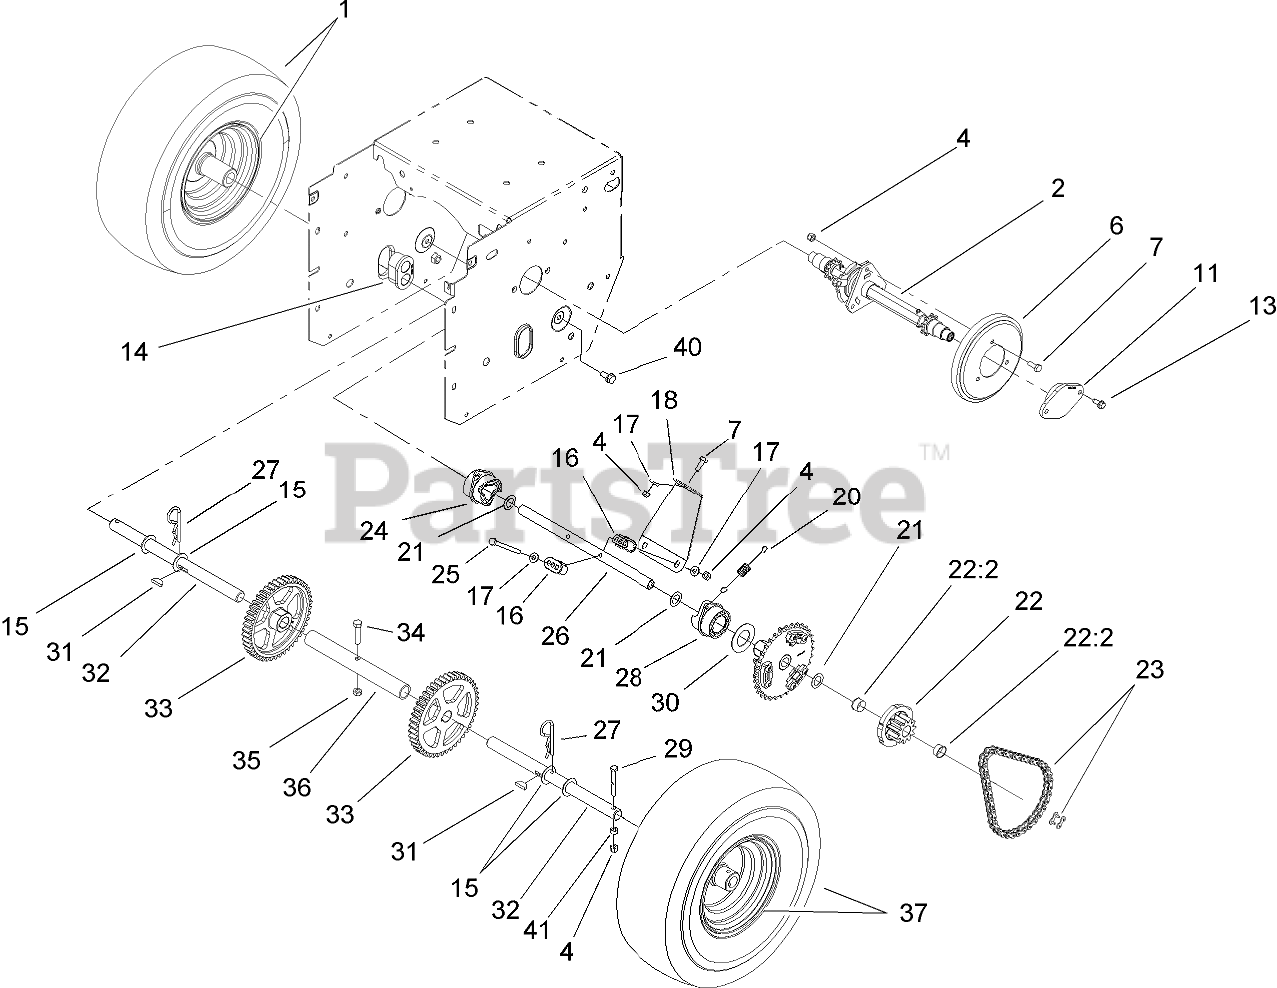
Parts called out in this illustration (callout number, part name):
1	RH WHEEL AND TIRE ASM
1	RIM-TIRE
2	CLUTCH HEXSHAFT ASM
4	NUT-LOCK, NI
6	WHEEL-FRICTION
7	SCREW-HH
11	RETAINER-BEARING
13	SCREW-HWH
14	BEARING-AXLE
15	WASHER-THRUST
16	GUIDE-COLLAR
17	WASHER-FLAT
18	BRACE-COLLAR, SHIFT
20	SPRING-EXTENSION
21	WASHER-FLAT
22	11T GEAR ASM
22:2	BUSHING-FLANGE
23	CHAIN-ROLLER
23	LINK-CONNECTING
24	COLLAR-SHIFT, RH
25	SCREW-HH
26	SHAFT-INTERMEDIATE
27	PIN-HAIR
28	COLLAR-SHIFT, LH
29	SCREW-HH
30	WASHER-THRUST
31	KEY-WOODRUFF
32	SHAFT-AXLE
33	GEAR-AXLE, 44 TOOTH
34	SCREW-HH
35	NUT-LOCK, NI
36	TUBE-AXLE
37	LH WHEEL AND TIRE ASM
37	RIM-TIRE
40	SCREW-HWHTF
41	SPACER-BLADE, ROTOR
